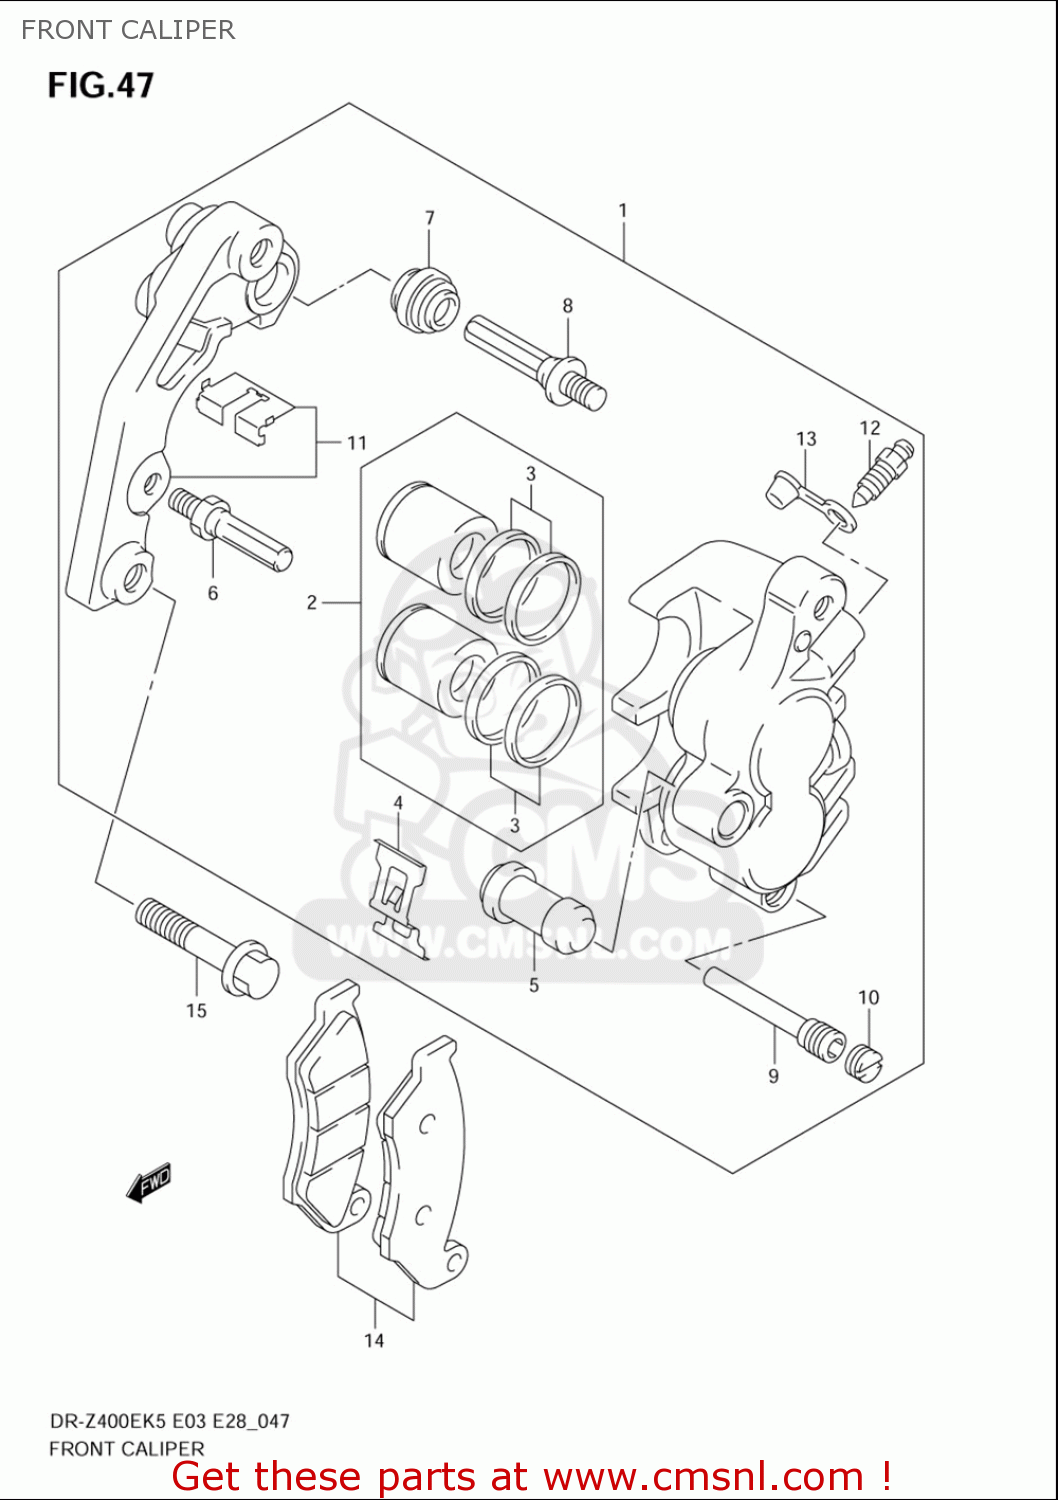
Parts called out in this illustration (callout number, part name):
1	CALIPER ASSY,F
2	PISTON SET
3	SEAL SET,PISTON
4	SPRING,PAD
5	BOOT
6	BOLT
7	BOOT
8	PIN
9	PIN,HANGER
10	PLUG,PIN
11	BRACKET
12	BLEEDER
13	CAP,BLEEDER
14	PAD SET (NAS)
15	BOLT(8X40)
